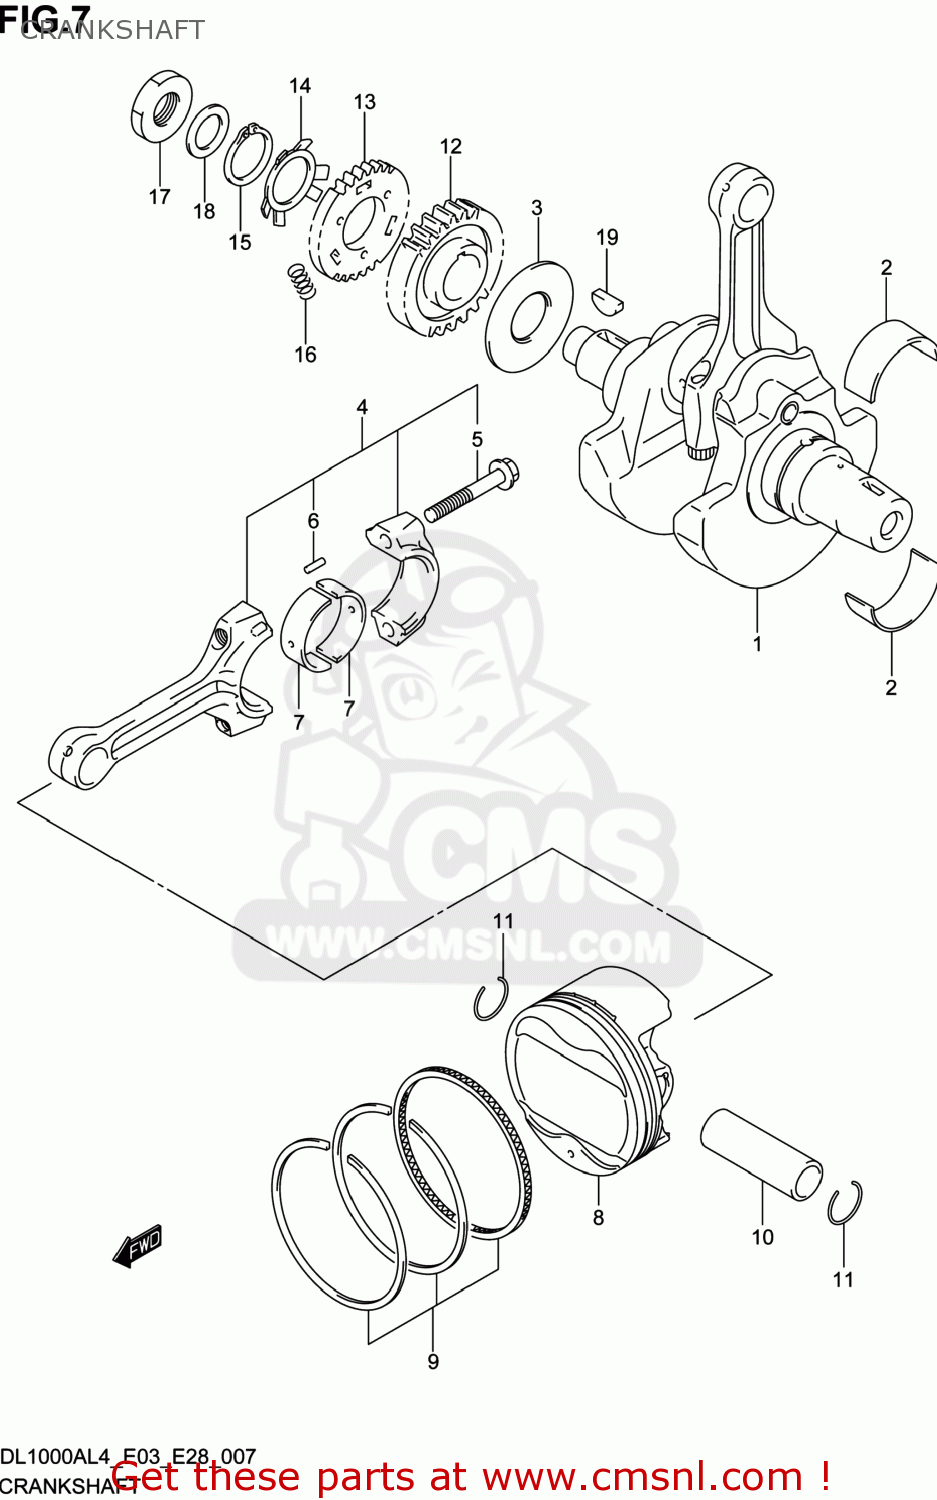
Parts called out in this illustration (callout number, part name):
1	CRANKSHAFT
2	BEARING,CRANKSHAFT
3	WASHER,CRANK THRUST
4	CONNECTING ROD ASSY
5	BOLT,CONNECTING ROD
6	PIN,CONNECTING ROD
7	BEARING,CRANK PIN
8	PISTON
9	RING SET,PISTON
10	PIN,PISTON
11	CIRCLIP
12	GEAR,PRIMARY DRIVE
13	GEAR,PRIMARY DRIVE SCISSORS
14	WASHER,PRI DRIVE
15	CIRCLIP
16	SPRING
17	NUT
18	WASHER
19	KEY
